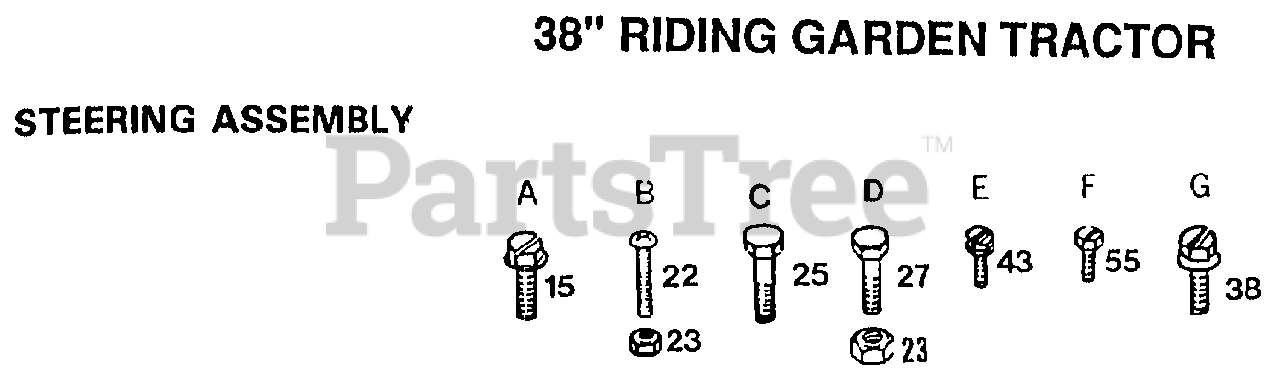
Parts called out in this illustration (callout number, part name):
15	SCREW
22	SCREW
25	SCREW SPECIAL
27	BOLT
38	SCREW LT
43	SCREW LT
